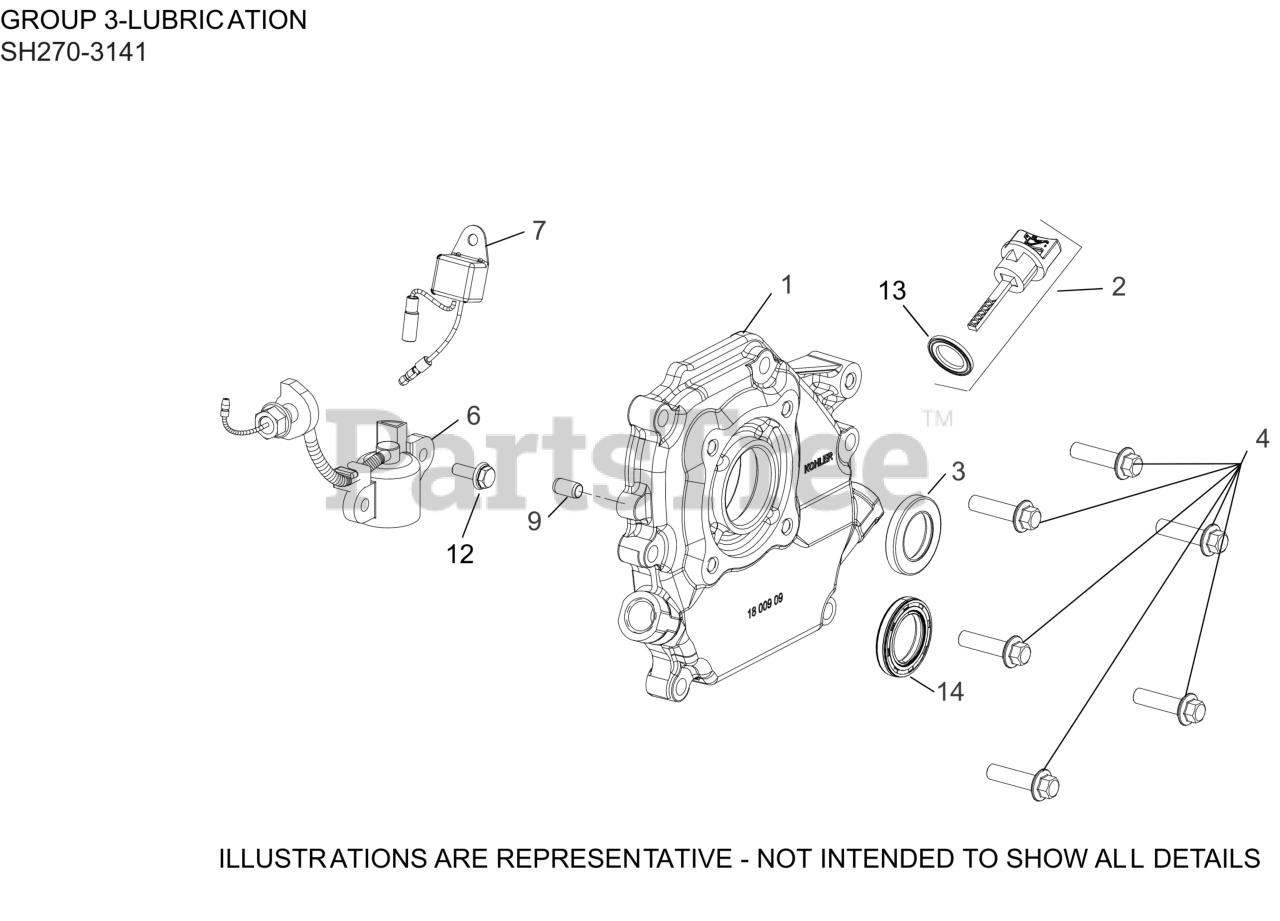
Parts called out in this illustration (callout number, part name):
1	PLATE, CLOSURE & BEARING
2	DIPSTICK ASSEMBLY
3	SEAL - USE 17 032 29-S
4	SCREW, CLOSURE PLATE
6	SWITCH, OIL SENSOR ASSEMBLY
7	CONTROL, OIL ALERT UNIT
12	SCREW, M6 X 16
13	SEAL, DIPSTICK
14	SEAL, OIL
15	DIPSTICK - USE 17 038 08-S
